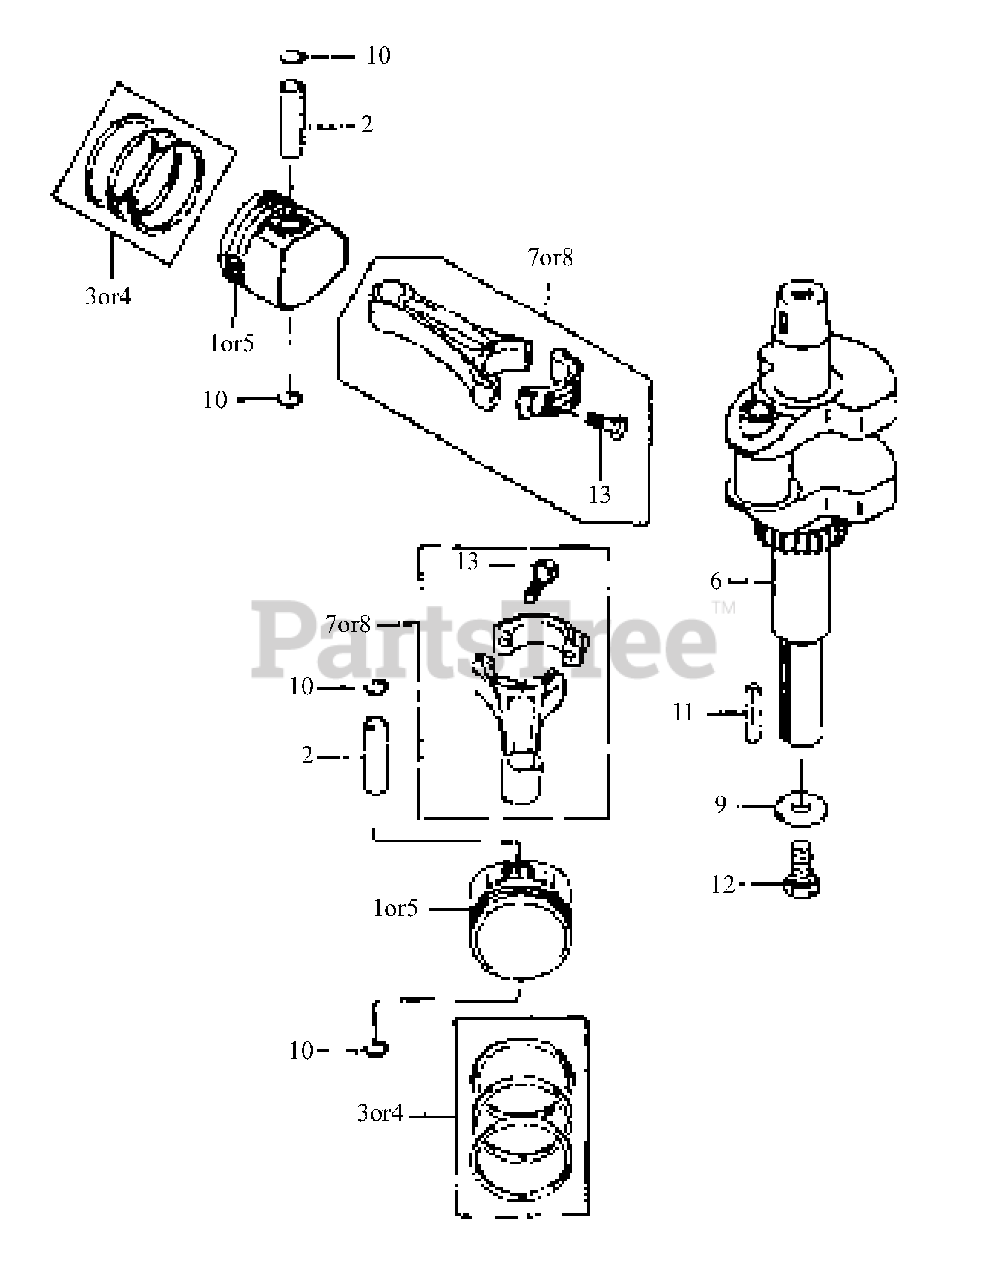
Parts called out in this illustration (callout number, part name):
1	Piston, Engine
3	Ring, Set Piston
4	Ring, Set Piston 0.050
5	Piston, Engine 0.050
6	Crankshaft, Comp.
7	Rod, Connecting u/s 0.050
8	Rod, Connecting Std
9	Washer 12.5x32x3.2
10	Ring, Snap
12	Bolt 7/16-20 unf
13	Bolt Flange
